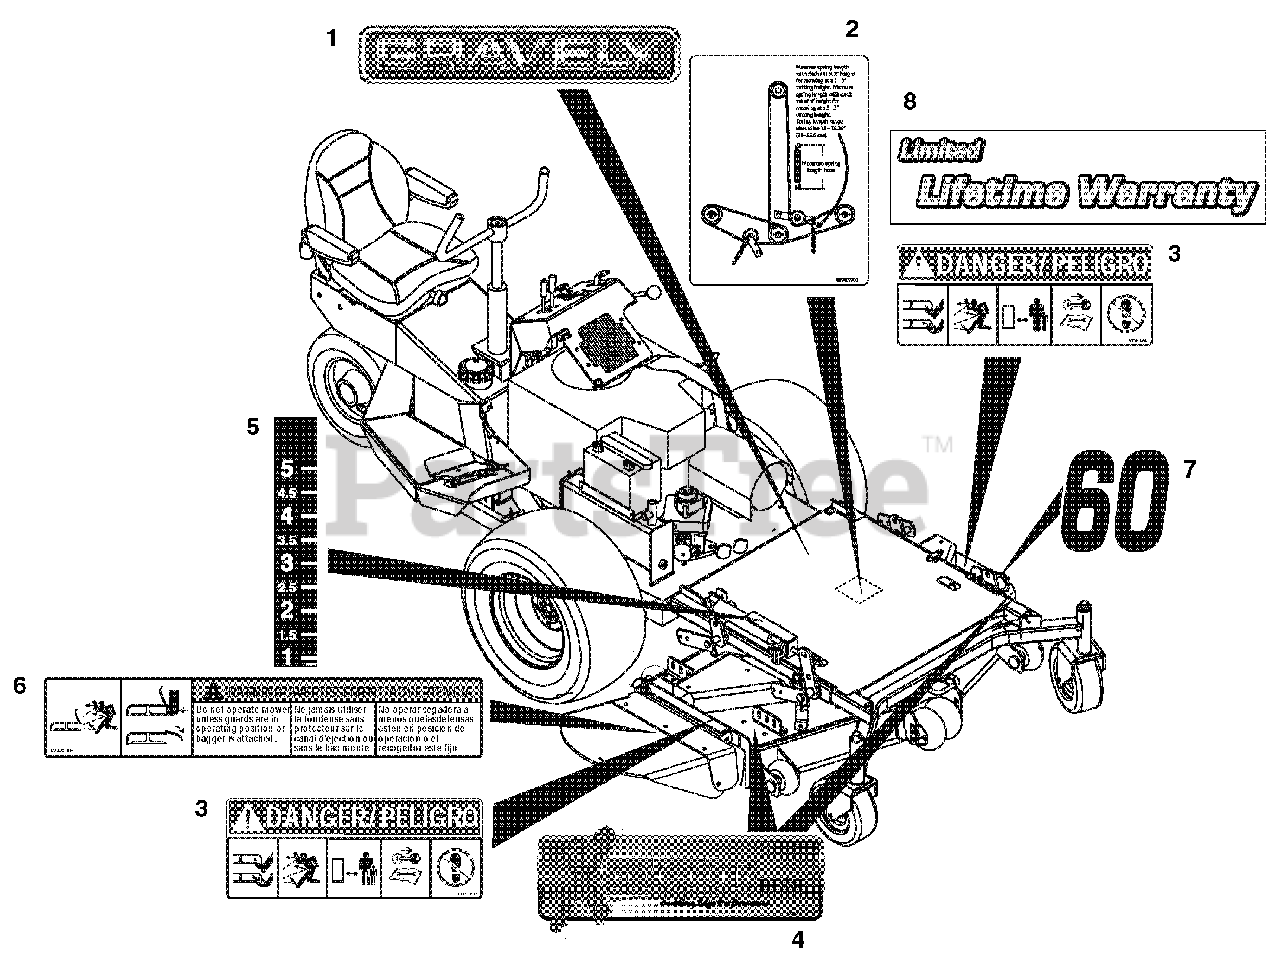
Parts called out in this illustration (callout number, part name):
1	Decal-15" Gravely Logo
2	Decal, Belt Diagram
3	Decal, Mower Pan Head Danger
4	Decal, X-Factor Deck
5	Height of Cut
6	Decal, Warning
7	Decal, 60
8	Decal, Limited Lifetime Warranty
